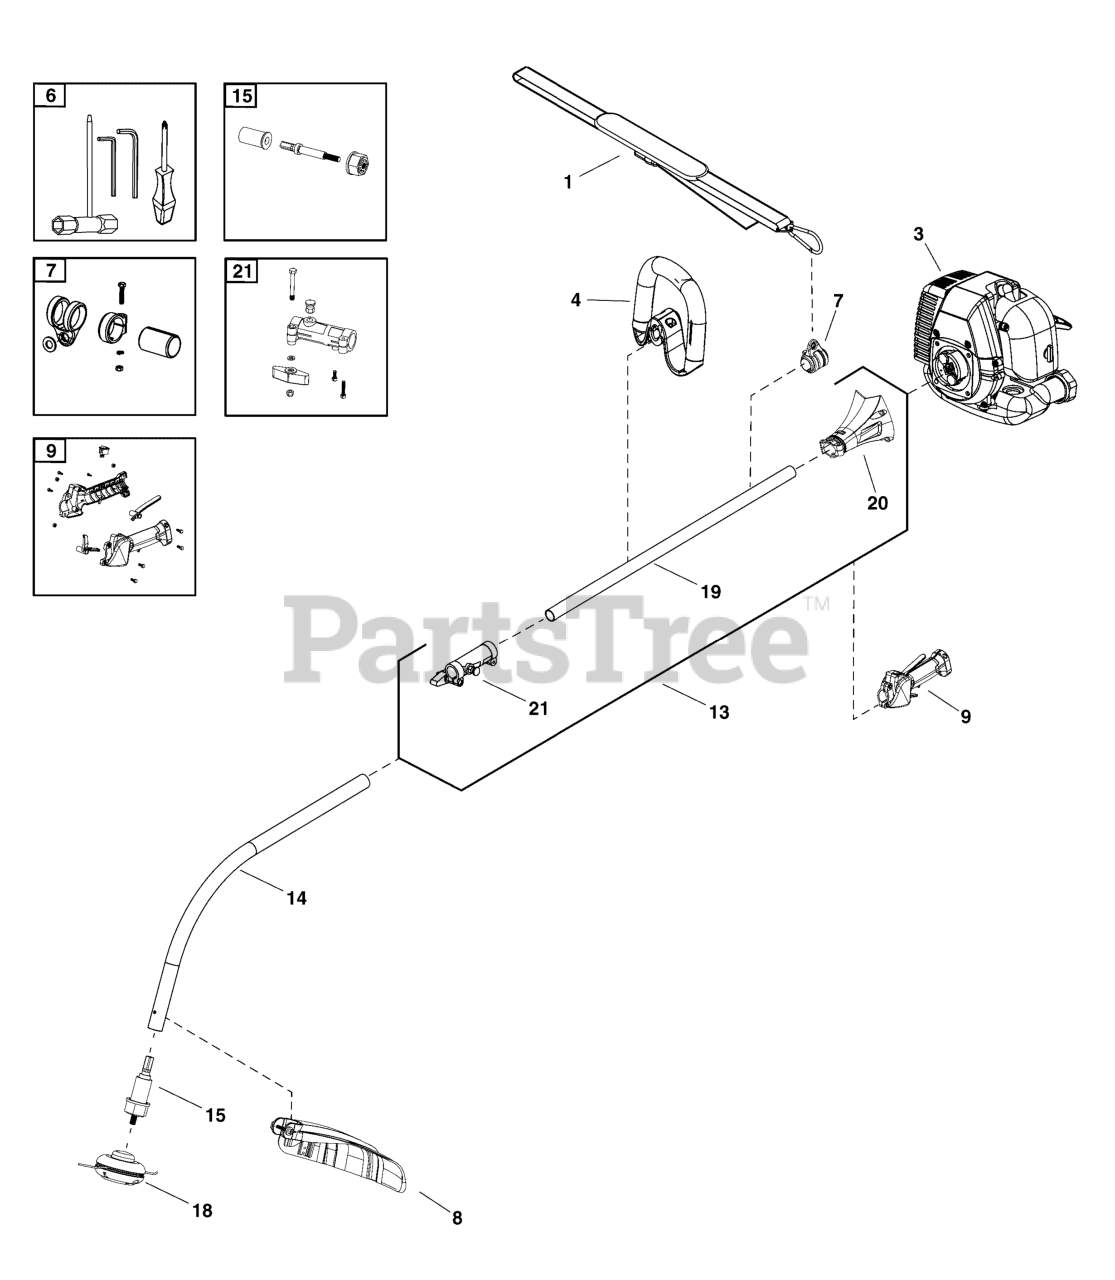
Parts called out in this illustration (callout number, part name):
1	HARNESS, Shoulder
3	ENGINE 25.4CC 2ST TRIMMER
4	HANDLE ASSEMBLY
6	TOOL KIT
7	BRACKET, Strap
8	GUARD ASSEMBLY, Bent Shaft
9	TRIGGER HOUSING ASSEMBLY
13	SHAFT ASSEMBLY, Upper
14	BENT SHAFT ASSEMBLY
15	GEAR HEAD ASSEMBLY, GSL HEAD
18	GATOR SPEEDLOAD HEAD PRO SM
19	UPPER DRIVE SHAFT ASSEMBLY
20	CLUTCH ASSEMBLY
21	COUPLING ASSEMBLY
